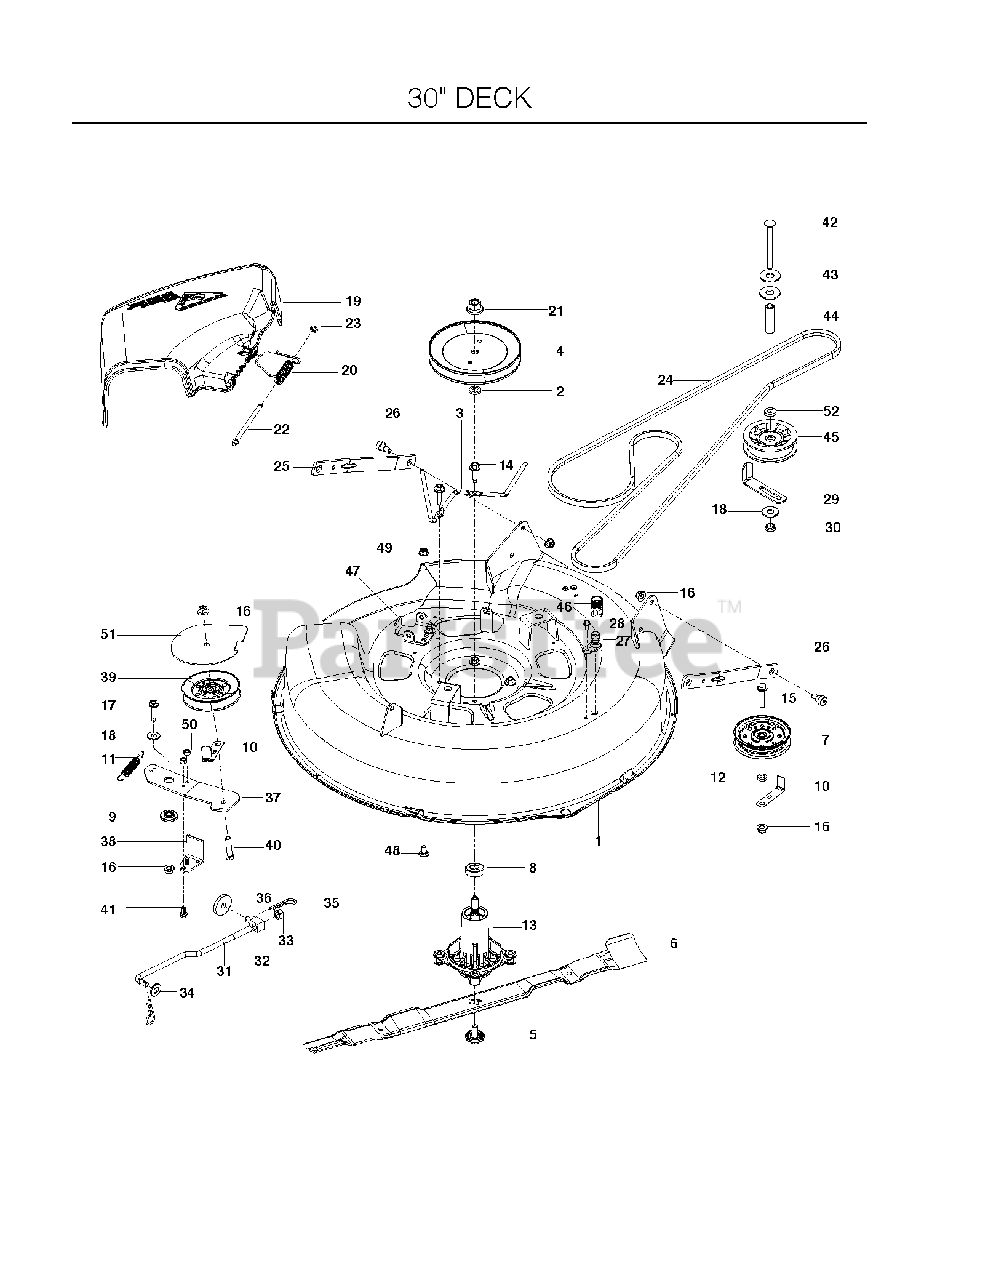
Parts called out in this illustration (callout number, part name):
1	DECK W/DECALS, SZ 30 BLUE
2	WASHER-SPACER
3	KEEPER, MANDREL BELT
4	PULLEY MANDREL 5.0"
5	BOLT.WASHER.ASM.7/16-2
6	BLADE.MOWER.BAGGING.30"
7	PULLEY.IDLER.FLAT.46.PR.DR.
8	BEARING, BALL
9	SPACER.RETAINER
10	KEEPER, BELT, BLACK
11	SPRING RETURN
12	WASHER 3/8 X 3/4 X .187 TK
13	MANDREL GREASABLE
14	WASHER HEAD SCREW
15	BLT 3/8-16X1-3/4 WHIZLK ZN SP
16	NUT 3/8-16 HEX FLG NYLOC ZD
17	BOLT 3/8-16 X 1 1/2 ZINC CLEAR
18	WASHER 3/8 FLAT
19	SHIELD.DEFLECT.MWR.30S.BLACK
20	TORSION SPRING
21	LOCKNUT - 9/16
22	HINGE ROD
23	PUSH NUT
24	BELT, 100" EL
25	ARM, REAR DECK SUSP, BLK
26	SB 3/8-16 X 3/8 SKT HD ZD
27	PORT.WASHOUT
28	BOLT 1/4-20 X 1/2 HWST
29	GUIDE, BELT
30	NUT HEX 3/8-16 NYLON, THIN
31	LINK LIFT SUSP. FRONT MOWER
33	NUT, 7/16-20 HEX NYLOC ZC
34	WASHER 1/2" FLAT
35	HAIRPIN #4
36	SPINDLE WASHER
37	ARM, IDLER 30, BLK
38	ARM, LH BRAKE
39	Idler Pulley, 4.25
40	HCS 3/8C X 2
41	SCREW- 1/4-20 X 5/8
42	RHSNB 3/8-16 X 4 GR5 ZD
43	WASHER 7/16 FLAT ZD
44	SPACER .39 ID X 2.25
45	PULLEY, IDLER
46	COUPLING.QUICK CONNECT
47	BRKT.DEFLECTOR.38"2005+
48	CARRIAGE BOLT 5/16C X 5/8"
49	5/16-18 NYLOC FLANGE NUT
50	NUT 1/4-20 NYLOC
51	COVER, PULLEY, BLACK
52	WASHER 3/8 X 3/4 X .187 TK
